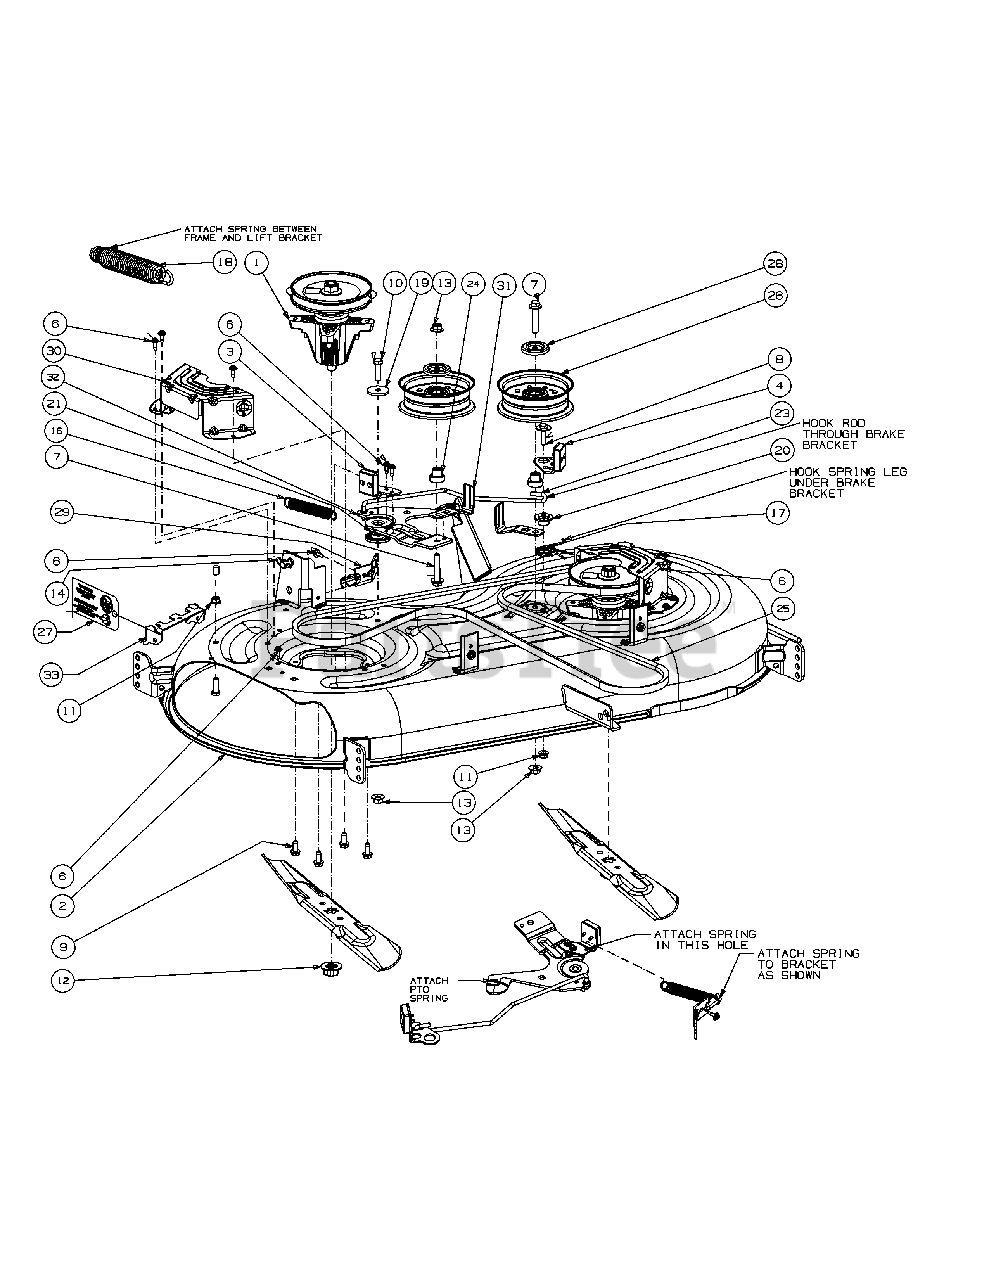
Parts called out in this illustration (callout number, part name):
1	Spindle Asm:Pulley:6.3 Dia
1	Shaft-Blade Spindle
1	Bearing, Ball
1	Spacer- .792 X 1.0
1	Housing-Deck Spindle
1	Pulley-Deck 5.4" D
1	Shield-Brg
1	Spacer .800 X 1.1
1	Nut-Flange 5/8-18 Flex
2	Deck 42"
3	Brake Asm:Deck:RH
3	Pad-Deck Brake
4	Brake Asm:Deck:LH
4	Pad-Deck Brake
5	Screw-Hex Cap
6	Screw-Hxacrnwsh M6
7	Screw Hhcs 3/8-16 X 2.0
8	Screw Hhcs 5/16-18X1.25
9	Screw-Hex Wash Hd
10	Screw-Hex 3/8-16X1
11	Nut-Flglk 5/16-18
12	Nut-Hex Flange 5/8
13	Nut-Flange Lock
14	Pin-Bow Tie Cotter
16	Spring - Extension
17	Spring-Torsion Lt5/Nx15
18	Spring-Lift Assist
19	Wash:Flat:.390 X 1.500 X .134
20	Spacer-Shoulder .7
21	Spacer-Shoulder
22	Blade:Cut:21.23" 2-In-1
23	Rod-Deck Brake
24	Spacer-Shoulder
25	Belt:V Typ:A Sec X 99.75
26	Pulley-Idler 4.50"
28	Cap-Idler Pulley
29	Bracket-Engage Cable
30	Cover-Deck Belt 42
31	Keeper-Belt
32	Bracket-Idler Pivot 42"
33	Bracket
